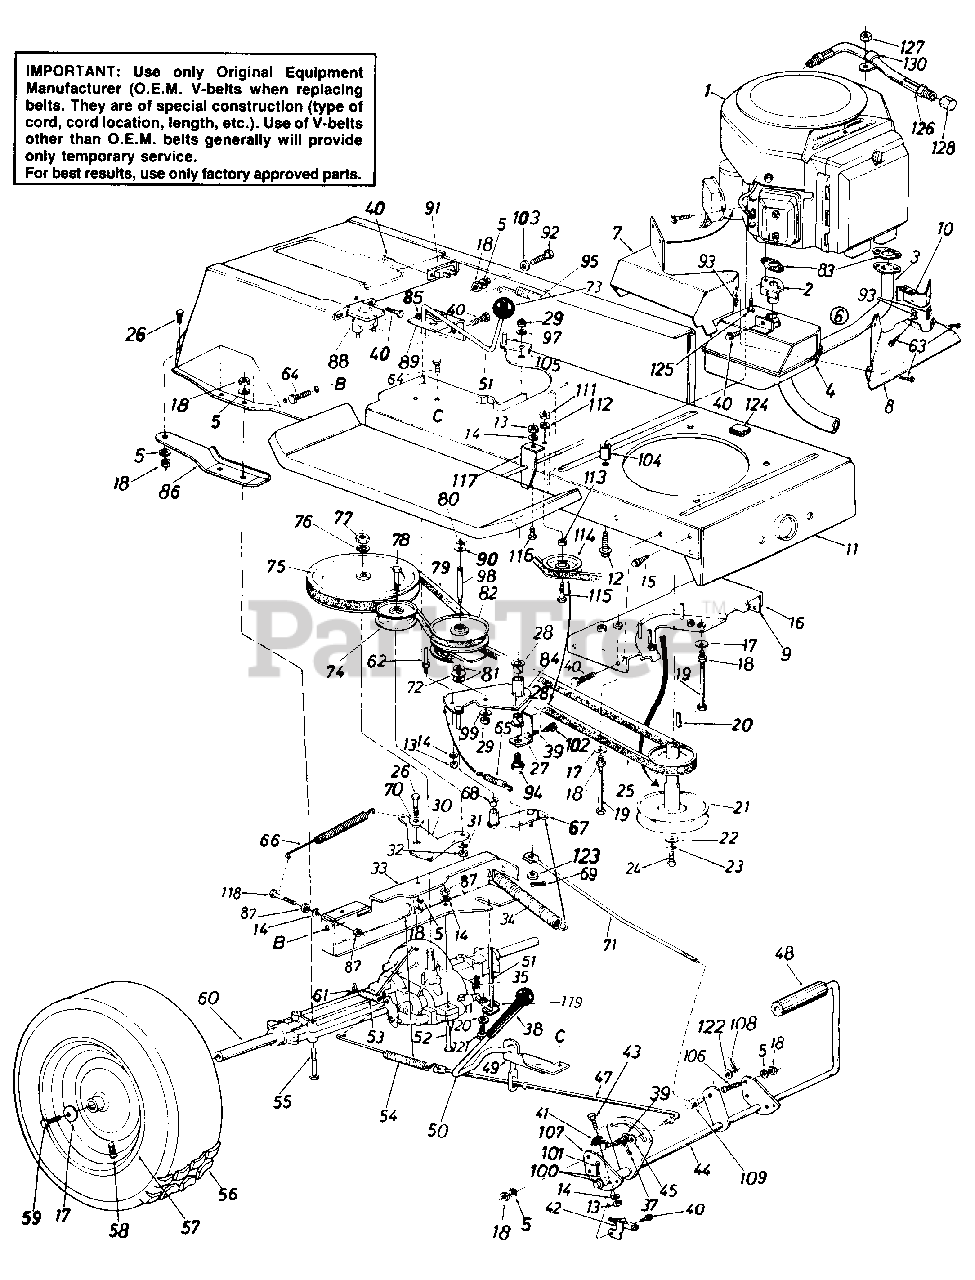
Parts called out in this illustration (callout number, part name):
1	Engine
2	Inlet Tube Ass'y.
3	Formed Tube Ass'y.
4	Exhaust Muffler Sub Ass'y.
5	L-Wash. 5/16" I.D.
6	Exhaust Muffler Comp.
7	Muffler Heat Shield
8	Front Heat Shield
9	Brake Cable Brk't.
10	Front Heat Shield Ext.
11	Lower Frame Ass'y.
12	Hex Wash. Hd. TT-Tap Scr. 3/8-16 Thd.
13	Hex Nut 1/4-20 Thd.
14	L-Wash. 1/4" I.D.
15	Hex Wash. Hd. AB-Tap Scr. 5/16" x.75" Lg.
16	Belt Guard Brkt. Ass'y.
17	Bell-Wash. .345" I.D. x .88"
18	Hex Nut 5/16-18 Thd.
19	Hex Bolt 5/16-18 x 4.00"
20	Sq. Key 1/4" x 1/4" X 2.00"
21	Engine Pulley
22	Fl-Wash. 7/16" I.D. x 1.25"
23	L-Wash. 7/16" I.D.
24	Hex Bolt 7/16-20 x 1.50" Lg.
25	Variable-Speed Belt
26	Hex Bolt 5/16-18 x .75" Lg.
27	Bearing Shaft Bracket Ass'y.
28	Flanged Nyliner Brg. 518" I.D. x .88" Lg.
29	Hex Nut 3/8-24 Thd.
30	Idler Bracket
31	L-Wash. 3/8" I.D.
32	Hex Nut 3/8-24 Thd.
35	Inter. Cotter Pin
36	Fl-Wash. .34" I.D. x .62" O.D. x .033
37	Cotter Pin 3/32" Dia. x .75"
38	Grip Black
39	Truss Mach. Scr. 5/16-18 x .75" Lg.
40	Hex Wash. Hd. Self-Tap Scr. 1/4-20 X .50" Lg.
41	Switch Actuator
42	Safety Switch
43	Hex Bolt 1/4-20 x 1.0" Lg.
44	Clutch & Brake Pedal Ass'y.
45	Fl-Wash.
47	Brake Rod 20.9" Lg.
48	Foot Pad
49	Brake Lever Bracket
50	Hill Holder Brake Handle
51	Shift Lever Ass'y.
52	Hex Bolt 1/4-28 x 1.75" Lg.
53	Ext. Spring .38" O.D. x 2.5"
54	Ext. Spring .59" O.D. x 7.08"
55	Hex Bolt 5/16-18 x 2.75"
58	Air Valve
59	Hex Bolt 5/16-24 x .75" Lg.
60	Transaxle Complete R.H.
61	Brake Return Spring Anchor
62	Belt Guard Pin 1/4-20 Thd.
63	Hex AB-Tap Scr. #10 x .5" Lg.
64	Hex Wash. TT-Tap Scr. 5/16 x .62" Lg.
65	Ext. Spring
66	Ext. Spring .62" O.D. x 6.12"
68	Flanged Bearing
69	Cotter Pin 3/32" Dia.
70	Shoulder Spacer .500" Dia. x.27" Lg.
71	Speed Control Link
72	Truss Bearing .56 Dia. x 1.25"
73	Ball Knob
74	Fl-Idler Pulley 3.25" x .75"
75	1/2" "V"-Pulley 8.0" O.D. x .501 " I.D.
76	L-Wash. 1/2" I.D.
77	Hex Jam Nut 1/2-20 Thd.
78	Hex Bolt 3/8-24 x .75" Lg.
79	Variable Speed Belt
80	Snap Ring .56" Dia.
81	Fl-Wash.
82	Variable Speed Pulley Ass'y. 5" O.D.
83	Gasket
86	Transaxle Support Brkt. R.H.
87	Hex Nut 1/4-28 Thd.
88	Solenoid
89	Shift Lever Bracket
90	Teflon Washer
91	Circuit Breaker
92	Hex Bolt 5/16-18 x 1.50"
94	Shld. Bolt 3/8-24 x 3.12" Lg.
95	Ext. Spring .99" O.D. x 11.0"
97	Bell-Wash. .38" I.D. x .88"
98	Shaft .56" Dia. x 3.875" Lg.
99	Bell-Wash. .39" I.D. x 1.12"
100	Fl-Wash.
101	Cotter Pin 3/32" Dia. x .75"
102	Hex Wash. Hd. Scr. 5/16-18 x.62" Lg.
103	Fl-Wash. .34" I.D. x 1.12" O.D.
104	Spacer 5/1 6" I.D.
105	Belt Guard
106	Hex Bolt 5/16-18 x .75" Lg.
107	Pedal Bracket
108	Cotter Pin 3/32 x .75"
109	Ferrule
111	Hex Nut 3/8"-16 Thd.
112	L-Wash. 3/8" I.D.
113	Fl-Wash. .390" I.D. x 1.12"
114	Fl-Idler w/Flanges 2.750
115	Hex Bolt 3/8-16 x 2.00" Lg.
116	Hex Bolt 1/4-20 x .62" Lg.
117	Spring Hanger Bracket
118	Hex Bolt 1/4-28 x 1.25" Lg.
119	Shift Lever Link Ass'y.
120	Bell-Wash. .265 I.D. x .75 O.D.
121	Hex Bolt 1/4-28 x .62" Lg.
122	Fl-Wash. .385" I.D. x .62" O.D.
123	Fl-Wash. .34" I.D. x .68" O.D.
124	Foam Strip
125	Hex Bolt w/Washer
126	Oil Drain
127	Hex Jam Nut 318-16 Thd.
128	Cap Oil Drain
130	Clamp
